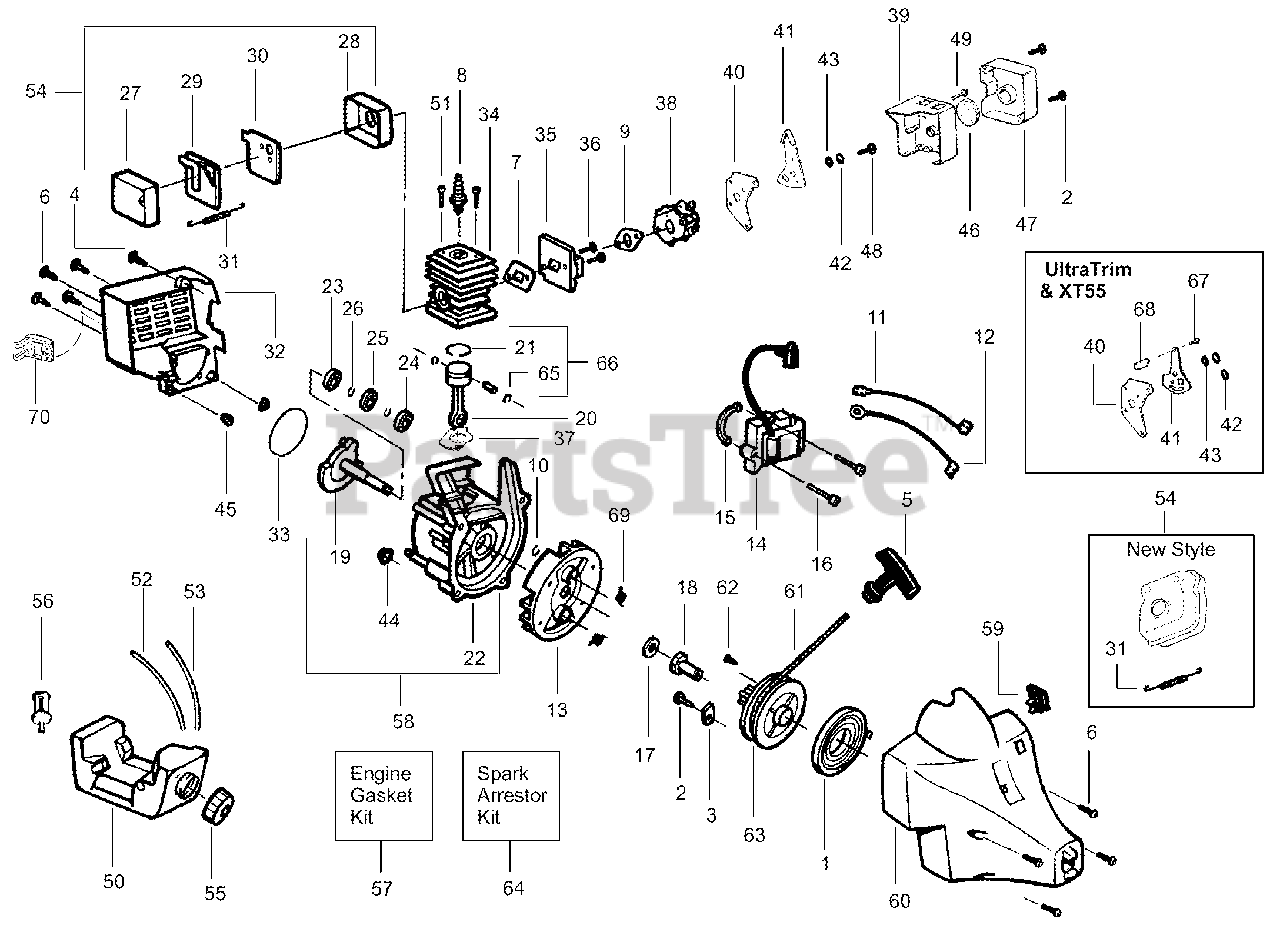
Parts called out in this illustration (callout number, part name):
1	Starter Spring
3	Retainer-Can
5	Starter Handle
6	Screw
7	Gasket-Cylind./Carb.
8	Spark Plug (RCJ 8Y)
9	Gasket-Carb.
10	Retainer Ring-C'shaft
11	Lead Wire Ass'y.
12	Ground Wire Ass'y.
13	Assy-Flywheel
14	Ignition Module
15	Spacer-Module
17	Washer-Flat
18	Drive Coupling
19	Assy-Crankshaft
20	Connecting Rod Ass'y.
21	Piston Ring
22	Assy-Crankcase
23	Inner Bearing
24	Outer Bearing
25	C'case Seal
26	Retain. Ring-C'case
27	Muffler Body
28	Muffler Cover
29	Muffler Baffle-Exit
30	Muffler Baffle-First
31	Muffler Spring Old Style
31	Muffler Spring New Style
32	Rear Shroud
33	O-ring-C'case/Shrd
34	Cylinder Kit
35	Carb. Adaptor Kit
37	Gasket-Cylinder
38	Carburetor Ass'y Kit-Twist'N Edge, XT35 & TE400
38	Carburetor Ass'y Kit-Ultra Trim & XT55
40	Choke Plate Mounting
41	Choke Lever Twist'N Edge, XT35 & TE400
41	Choke Lever Ultra Trim & XT55
42	Spacer-Choke
44	Isolator-C'Case
45	Isolator-Shroud
46	Air Filter Foam
47	Air Filter Cover Twist-N-Edge, XT35 & TE400
47	Air Filter Cover Ultratrim & XT55
50	Fuel Tank Ass'y
51	Screw-Cylinder
52	Fuel Line (Large)
53	Fuel Line (Small)
54	Muffler Kit Old Style
54	Muffler Kit New Style
55	Fuel Cap Ass'y.
56	Fuel Pickup Ass'y.
57	Engine Gasket Kit
58	C'case & C'shaft Assy.
59	Switch
60	Assy-Fan Housing
61	Rope Kit
63	Starter Pulley Kit
64	Spark Arrestor Kit Old Style
64	Spark Arrestor Kit New Style
65	Piston Pin Retainer
66	Piston Kit
67	Screw-Choke Knob
68	Choke Knob
69	Starter Dog Spring
70	Guard-Muffler
